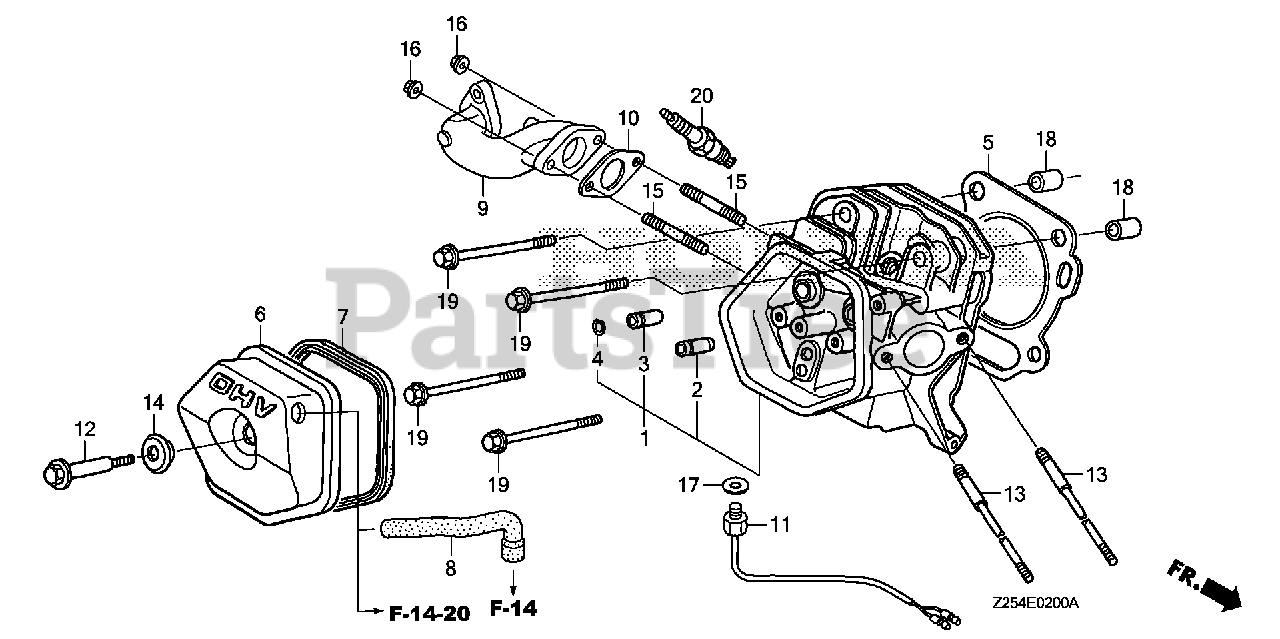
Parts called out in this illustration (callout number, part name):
1	CYLINDER HEAD
2	GUIDE, VALVE (OS)
3	GUIDE, EX. VALVE (OS)
4	CLIP, VALVE GUIDE
5	GASKET, CYLINDER HEAD Use up to Engine SN 2949254.
6	COVER, HEAD
7	GASKET, CYLINDER HEAD COVER
8	TUBE, BREATHER
10	GASKET, EX. PIPE
11	SENSOR ASSY., TEMPERATURE
12	BOLT, HEAD COVER
13	BOLT, STUD (8X126.5)
14	WASHER, HEAD COVER
15	BOLT 2, STUD (8X32)
16	NUT, FLANGE (8MM)
17	WASHER, PLAIN (8MM)
18	PIN A, DOWEL (12X20)
19	BOLT, FLANGE (10X80)
20	SPARK PLUG (BPR5ES) (NGK)
20	SPARK PLUG (W16EPR-U) (DENSO)
